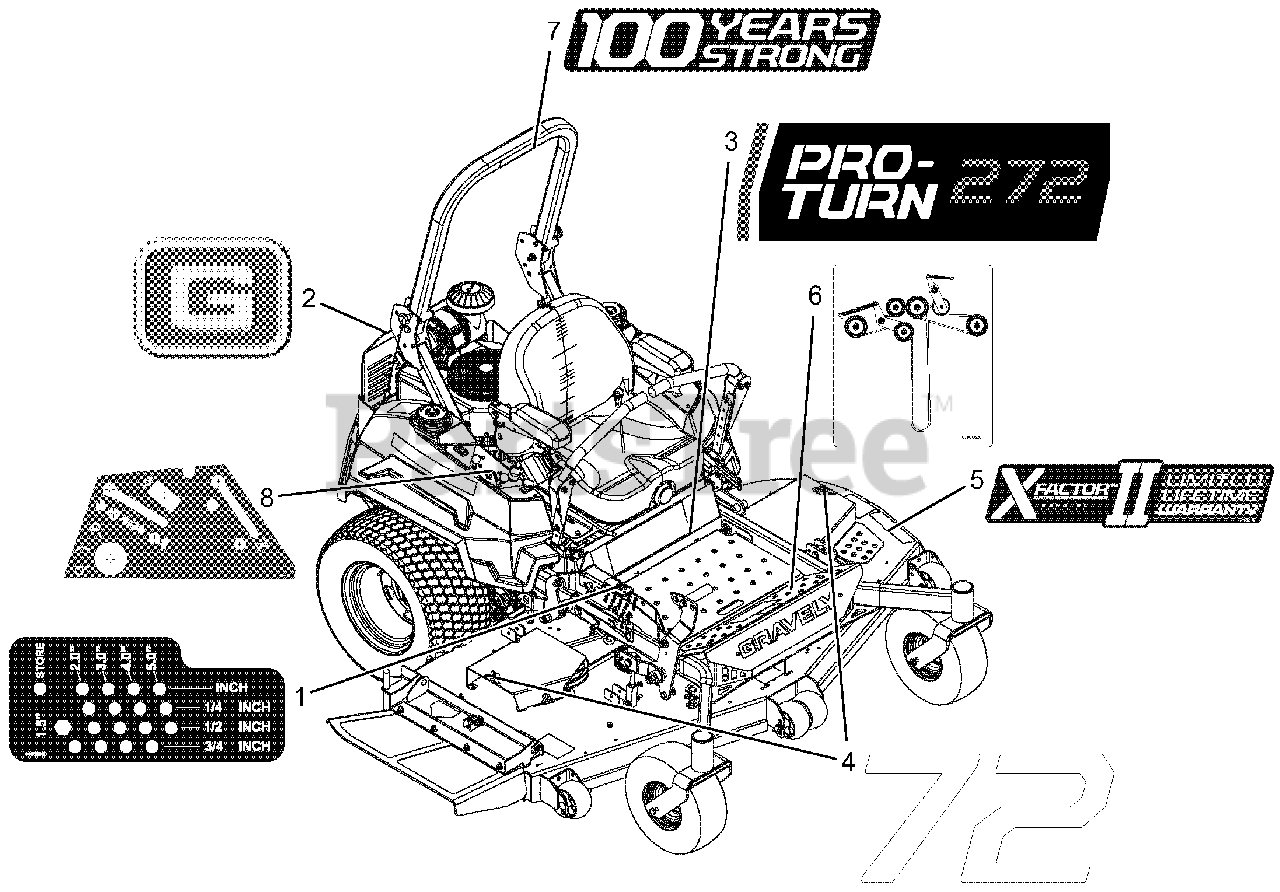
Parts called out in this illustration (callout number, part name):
1	DECAL, HEIGHT OF CUT
2	DECAL, GRAVELY BRAND
3	DECAL, PRO-TURN 272
4	DECAL, 72"
5	DECAL, X-FACTOR DECK
6	DCL,BELT ROUTE-RH BK-SIDE IDLR
7	DECAL, GRAVELY 100 YR
8	DECAL, NON-EFI CONTROL PANEL
